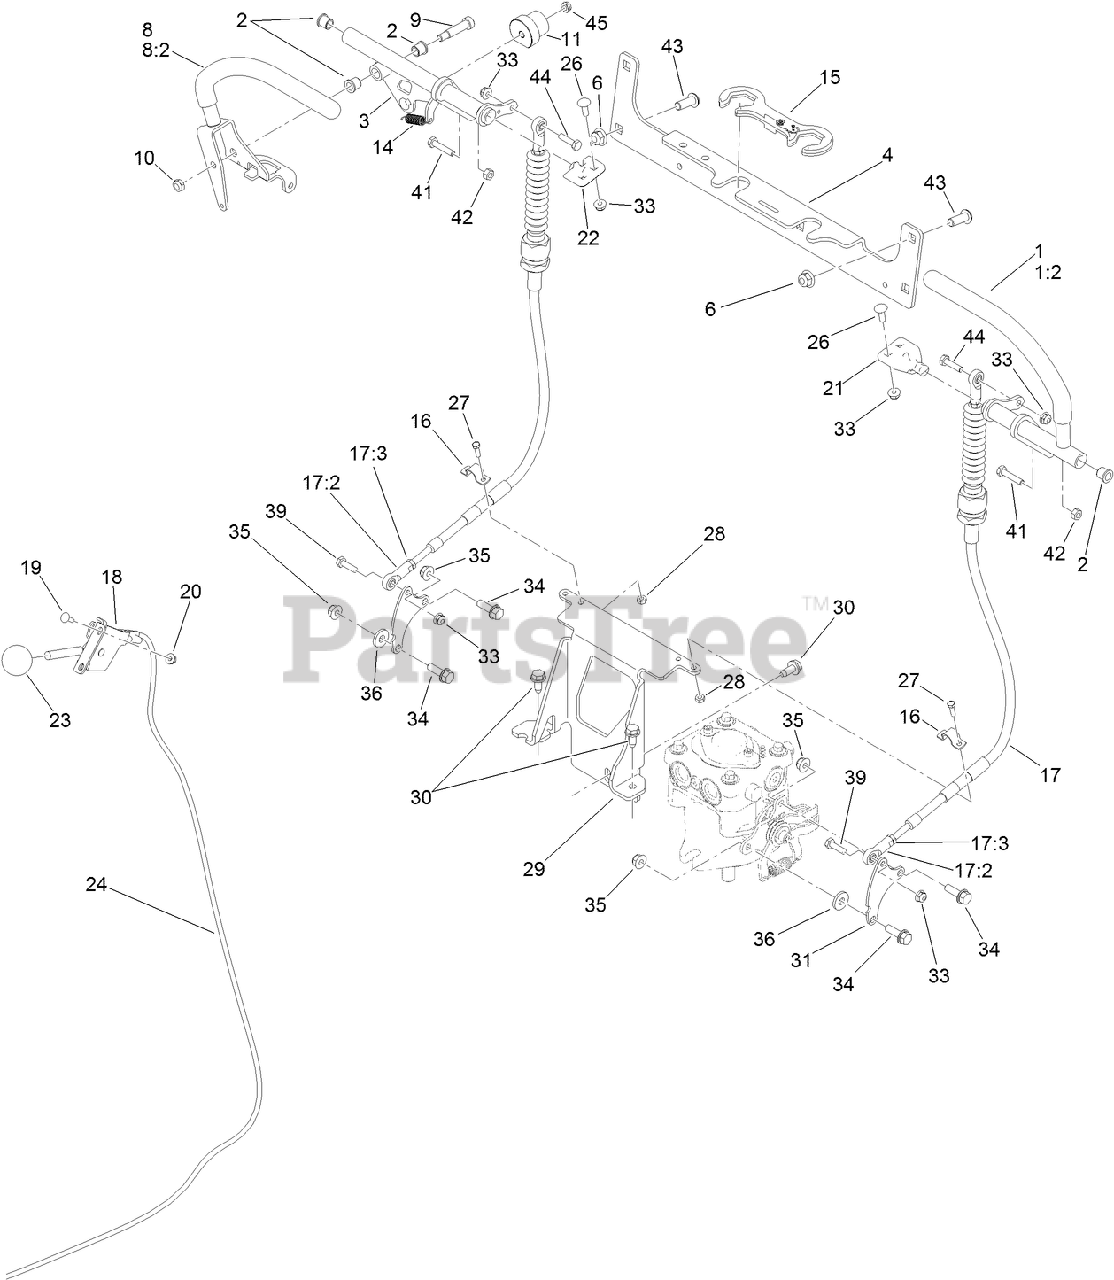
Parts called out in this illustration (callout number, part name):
1	LH LEVER ASM
2	BEARING
3	CONTROL-MOTION, RH
4	BRACKET-CROSS
6	NUT-HF, NI
8	RH LEVER ASM
9	SCREW-HSH
10	NUT-LOCK, NI
14	SPRING-EXTENSION
15	LOCK-CABLE
17	CABLE ASM
17:2	ROD END-BALL JOINT
17:3	NUT-JAM
18	LEVER-CONTROL
19	BOLT-CARR
20	NUT-LOCK, FLANGE
21	TAB-PIVOT, LH
22	TAB-PIVOT, RH
23	KNOB-BALL
24	CABLE-THROTTLE
26	BOLT-CARR
28	NUT-LOCK, NI
29	BRACKET-MOUNT, CABLE
30	SCREW-HWHTF
31	PLATE-CONTROL, PUMP
33	NUT-HF
34	SCREW-HHF
35	NUT-HF, NI
36	WASHER-FLAT
39	SCREW-HH
41	SCREW-HH
42	NUT-HEX
43	SCREW-HSBH
44	SCREW-HH
45	NUT-LOCK, NI
